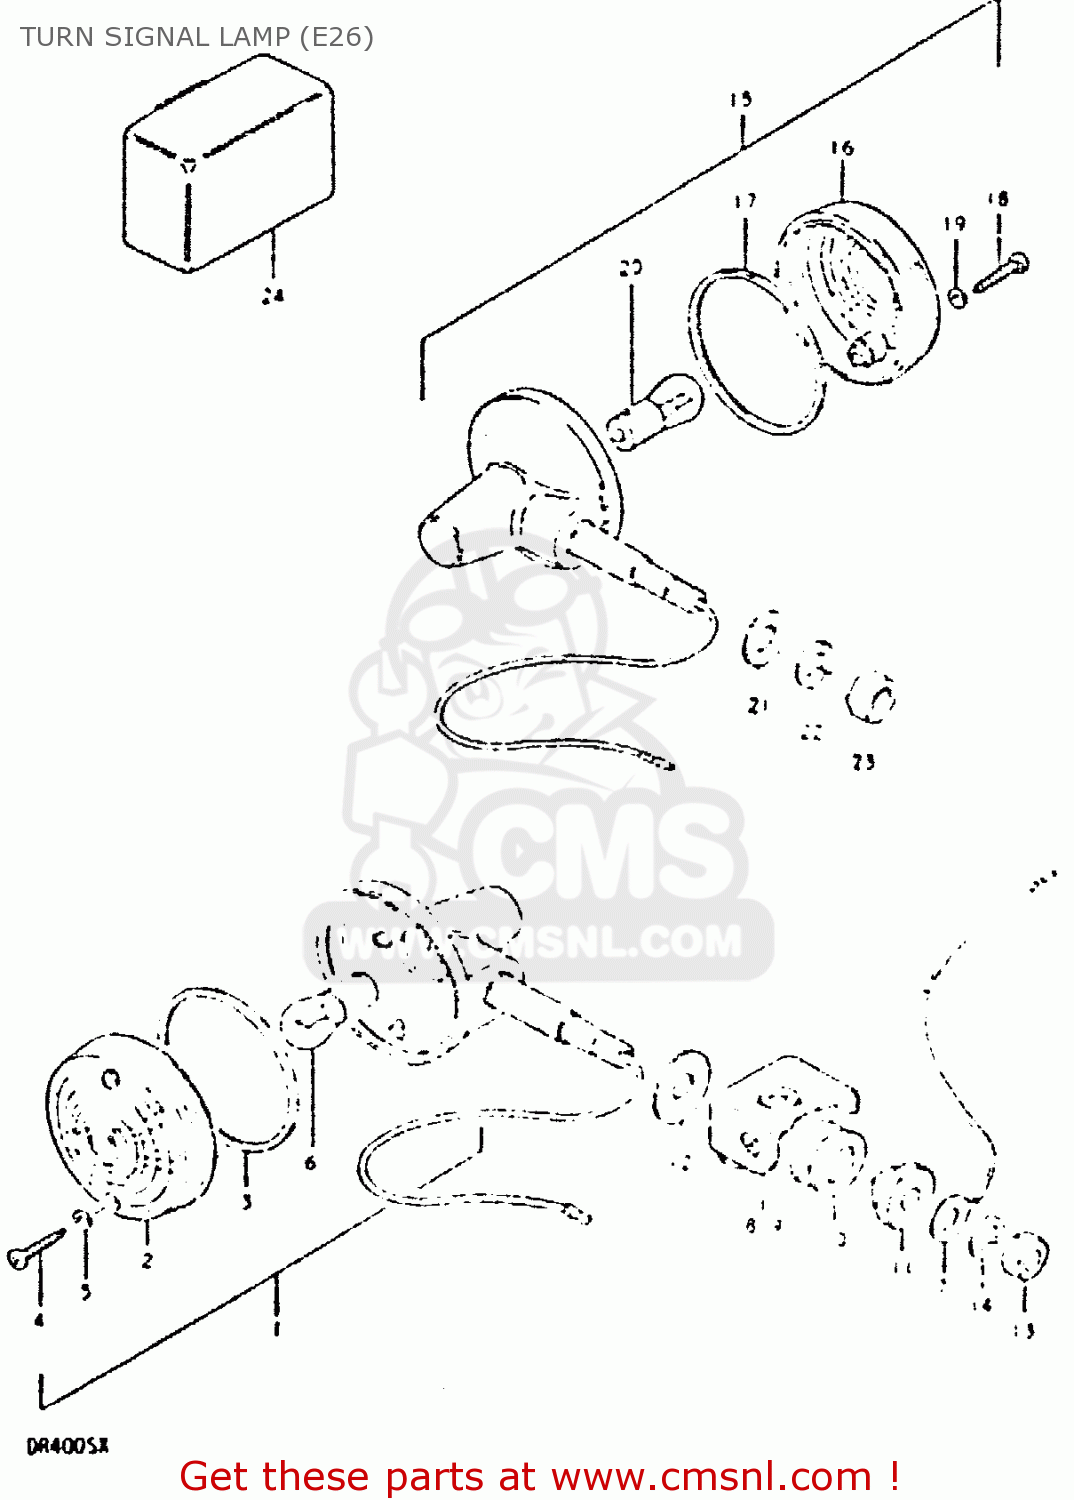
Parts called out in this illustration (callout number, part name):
1	LAMP, FRONT TURN SIGNAL
2	LENS
3	GASKET (NAS)
4	SCREW
5	GASKET (NAS)
6	BULB(6V/10W,STANLEY,A4117)
7	LEAD WIRE,EARTH
8	BRACKET, FRONT RH
9	BRACKET, FRONT LH
10	CUSHION
11	SPACER,TURN SIGNAL LAMP
12	WASHER (10.5X30X2.3)
13	NUT
14	LOCK WASHER
15	LAMP, REAR TURN SIGNAL
16	LENS
17	GASKET (NAS)
18	SCREW
19	GASKET (NAS)
20	BULB(6V/10W,STANLEY,A4117)
21	WASHER
22	LOCK WASHER
23	NUT
24	RELAY, TURN SIGNAL
